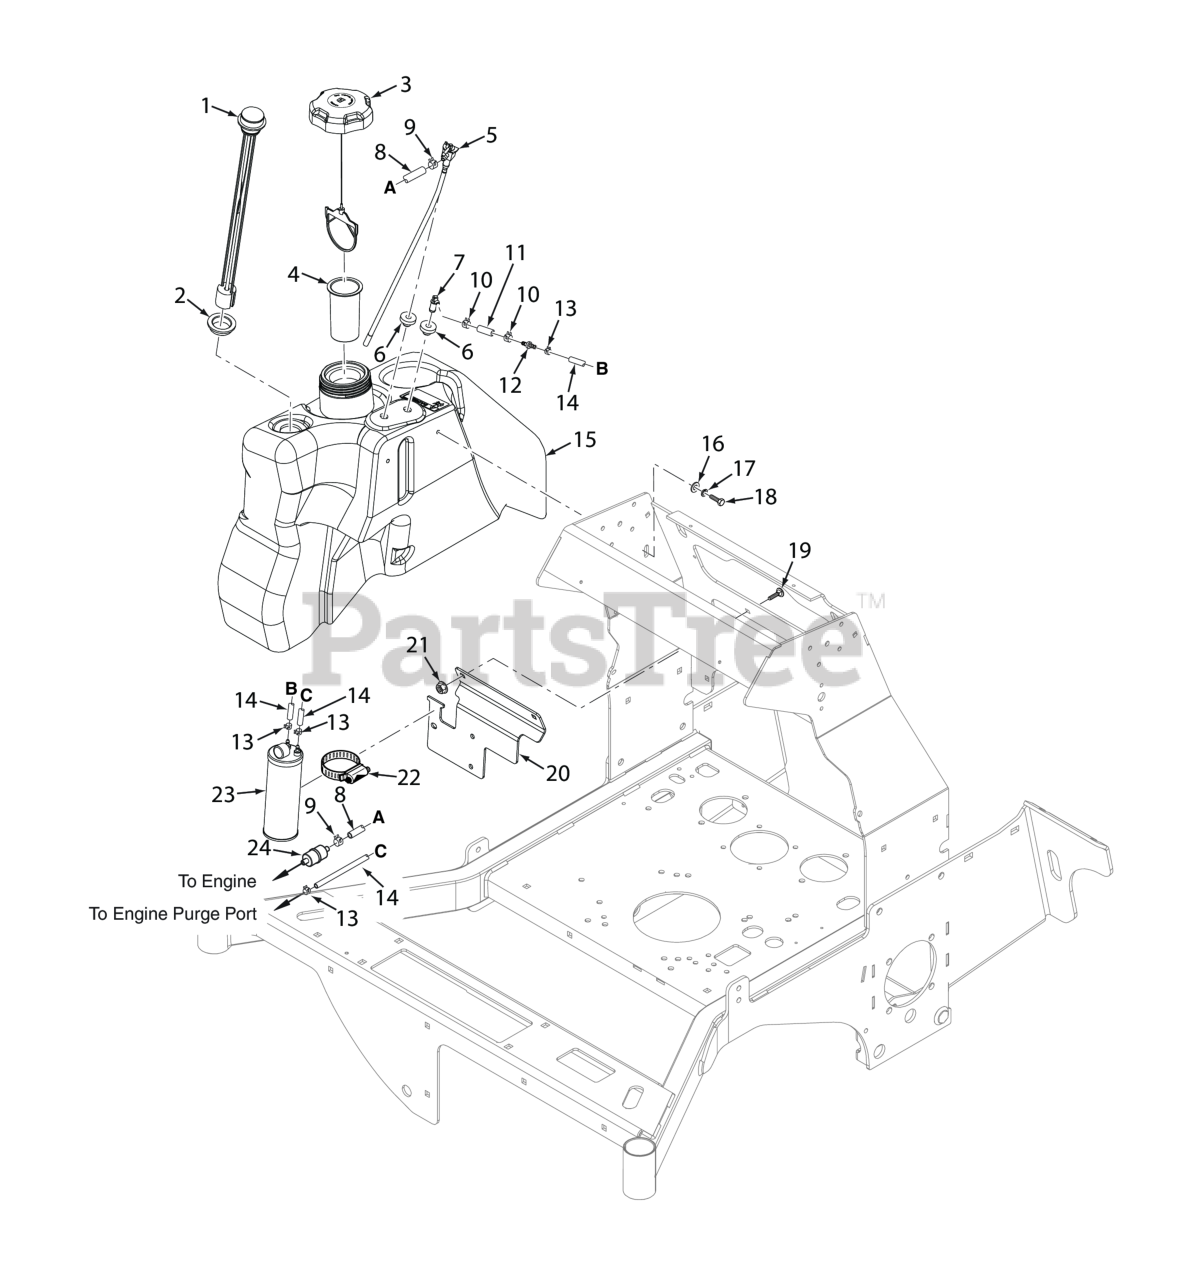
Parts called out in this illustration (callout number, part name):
1	Fuel Gauge Assy., 16-1/2"
2	Grommet, Fuel Gauge
3	Fuel Cap w/ Tether (E.P.A.)
3	Fuel Cap, Tethered - CA models only
4	Tube, Fuel Tank Insert - 4"
5	Valve, Fuel Shut Off
6	Bushing, 0.56" Dia. Viton
7	Remote Vent, With No Valve
8	Fuel Hose, 1/4" I.D. Non-Perm (791DFI Fuel Return) - Order by Inch
9	Clamp, Fuel Hose 1/4" Hose I.D.
10	CLAMP, FUEL HOSE(KAWASAKI ONLY)
11	Hose, 1/4" Vapor Recovery (order by inch)
12	Mender, 1/4 x 3/16 w/0.02 Hole
13	Clamp, Vapor Recovery Hose 3/16"
14	Hose, Vapor Recovery 3/16" (order by inch)
15	Fuel Tank Assy., Windstorm (Incl. #1,2,5,6,7)
16	Flatwasher, 5/16-.375 x .875 x .083 (35BV & 37BV-EFI)
17	Lockwasher, 5/16 (.317 x .586 x .078) Helical Spring
18	BOLT, SERRATED FLANGE HEX HEAD 5/16-18 X 3/4"
19	Bolt, 5/16-18 x .75 RHSN Carriage
20	Bracket, Hydro Tank Mounting
21	Nut, Serrated Flange 5/16-18 (Right Front Engine Mounting, Briggs and Kohler Only)
22	Clamp, 3-1/2" Max. Dia.
23	Carbon Canister - SVR-52V / SVR-61V
24	Fuel Filter
